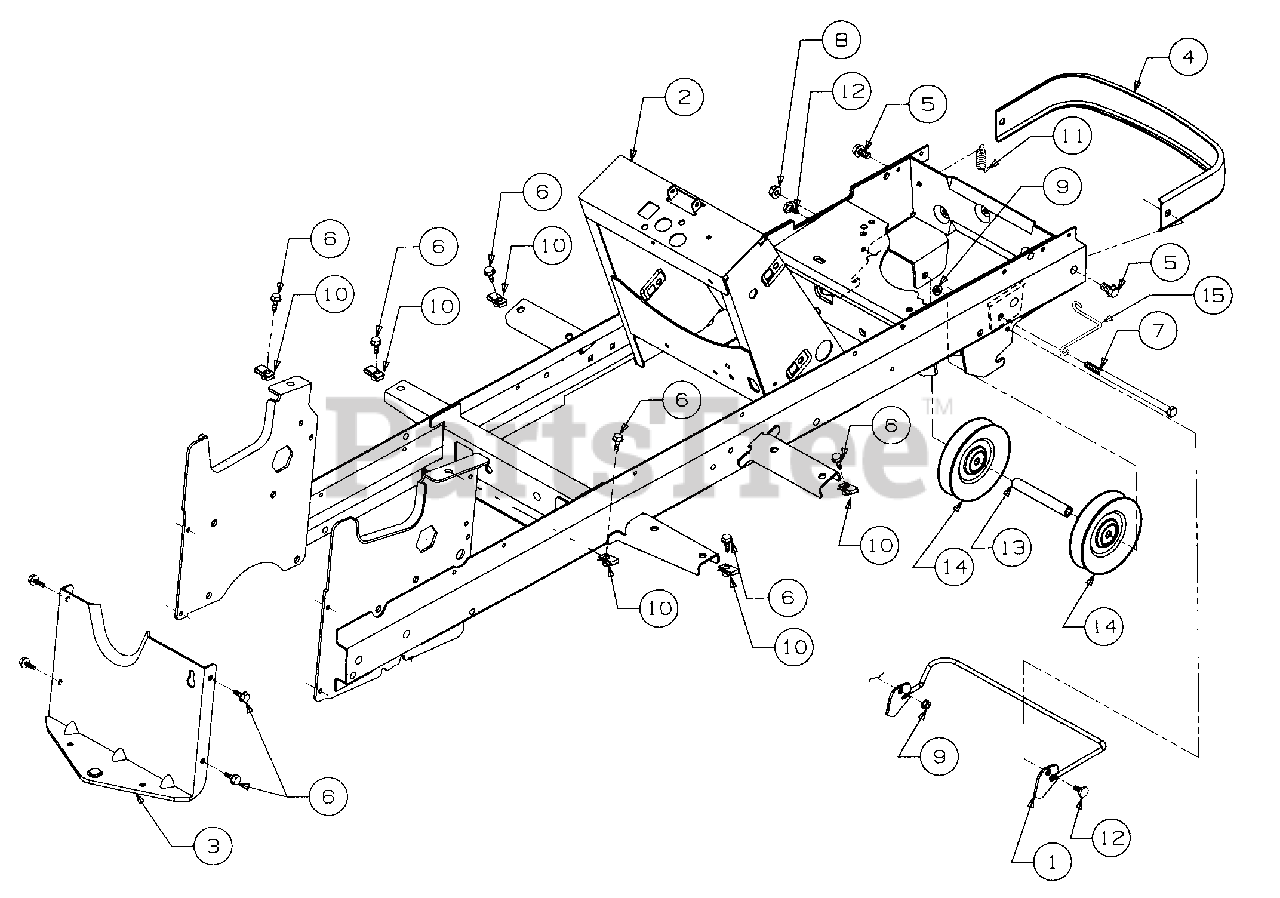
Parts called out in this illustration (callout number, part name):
1	Rod, Quick Attach
4	Bumper
5	Screw, Hex Wsh Hd Tapp 3/8-16 x .75
6	Screw, Hex Wsh Hd Tap 5/16-18 x .75
7	Screw, Hex Cap, 3/8-16 x 7.0
8	Nut, Hex Flange Lock, 3/8-16
9	Nut, Hex Flange Lock, 1/4-20
10	U-Nut, 5/16-18
11	Spring, Latch
12	Bolt, Shoulder
13	Spacer, Idler, .407 x .720 x 4.38
14	Pulley, Idler
15	Belt Guide
